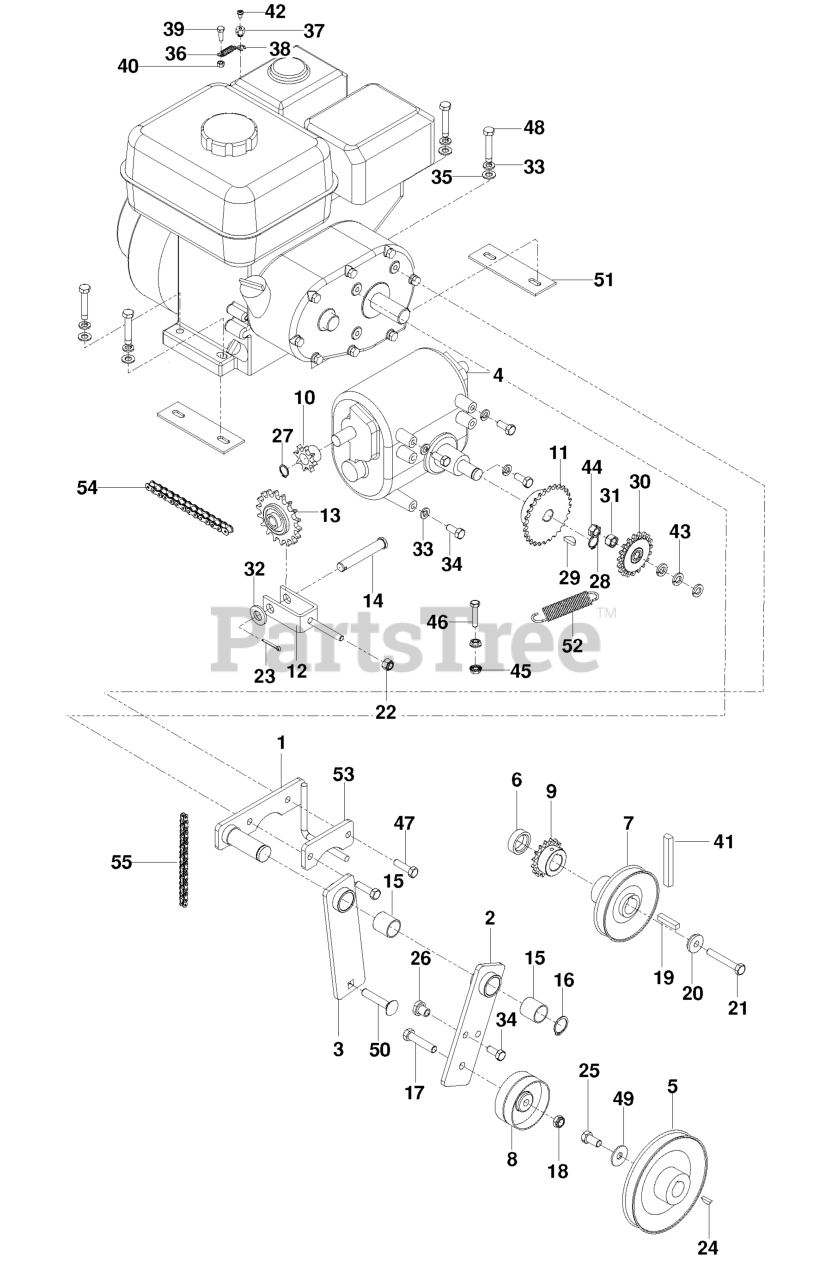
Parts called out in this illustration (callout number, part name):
1	IDLER PIVOT, BLACK
2	BELT IDLER W/BUSHING
3	CHAIN IDLER W/BUSHING
4	TRANSMISSION-4 SP SOD CUTTER
5	PULLEY - 5.25 A
6	SPACER - PTO SHAFT
7	PULLEY - 3.75 A
8	PULLEY, IDLER 2 3/4 OD PAINTED
9	SPROCKET, ENGINE
10	SPROCKET #40 CHAIN
11	SPROCKET, TRANSMISSION
12	KIT TENSIONER ASSY/DRIVE CHAIN
13	SPROCKET, CHAIN TENSIONER
14	PIN CLEVIS 1/2 X 3 ZD
16	RETAINING RING, 7/8"
17	HCS 3/8-16 X 1 3/4 GR5
18	NUT HEX 3/8-16 NYLON, THIN
19	KEY 7MM SQ X 33MM ENGINE
20	WASHER - STEPPED
21	HCS M8-1.25 X 55MM GR8.8 ZD
22	NUT 5/16 NYLOC
23	PIN COTTER 1/8 X 1 ZD
24	KEY-WOODRUFF, #6
25	HCS 3/8F X 3/4
26	SPRING ANCHOR
27	RING RETAINING 9/16 EXT PLAIN
28	RETAINER RING
29	KEY, #9 WOODRUFF
30	SPROCKET - IDLER 35 PITCH
31	NUT 3/8-16 NYLOC
32	WASHER 1/2" FLAT
33	WASHER.LOCK.HVY.HLCL.SPR.5/16
34	HCS 5/16C X 3/4
35	FLAT WASHER 5/16 SAE
36	SPRING, THROTTLE, HONDA ENGINE
37	CLAMP, THROTTLE CABLE
38	CLIP, THROTTLE HONDA
39	HCS M5-0.8 X 16MM GR 8.8 ZD
40	NUT 5MM-.8 HEX ZD
41	V-BELT, SOD CUTTER
42	SCREW METRIC SPECIAL X 1/4 ZN
43	SLW 3/8 STD
44	NUT 3/8C CENTERBLOCK
45	NUT 1/4-20 HEX FLG LK ZD
46	BOLT HEX 1/4 X 1-1/4
47	HCS M8-1.25 X 30MM
48	HCS 5/16C X 1 3/4
49	SPRING WASHER - .38
50	RHSNB 3/8C X 2
51	PLATE KIT, ENG, HONDA &5.5 B&S
52	SPRING AXLE AERATOR
53	KEEPER - CHAIN, BLACK
54	CHAIN,TRANSMISSION #35
55	CHAIN, 57.5 TRANS #40
